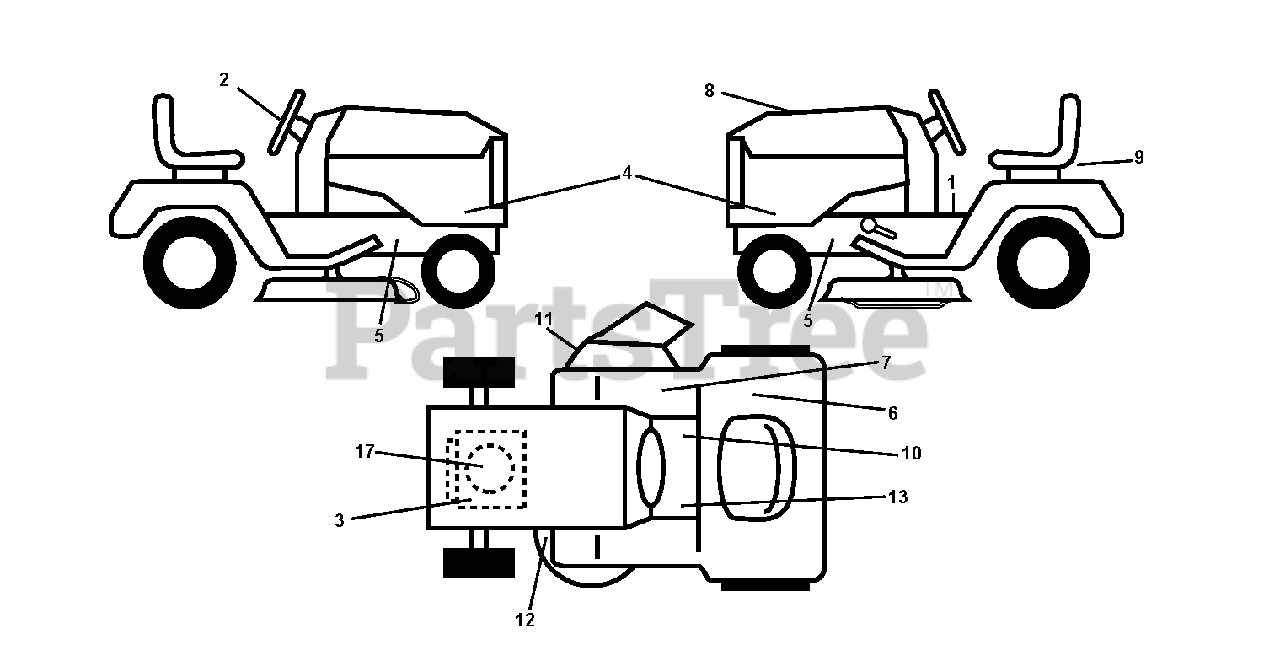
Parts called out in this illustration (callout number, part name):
9	DECAL BTRY SYMBOLS
10	DECAL PARK BRAKE
11	DECAL, WARN. DEFLECT/CTFGR
